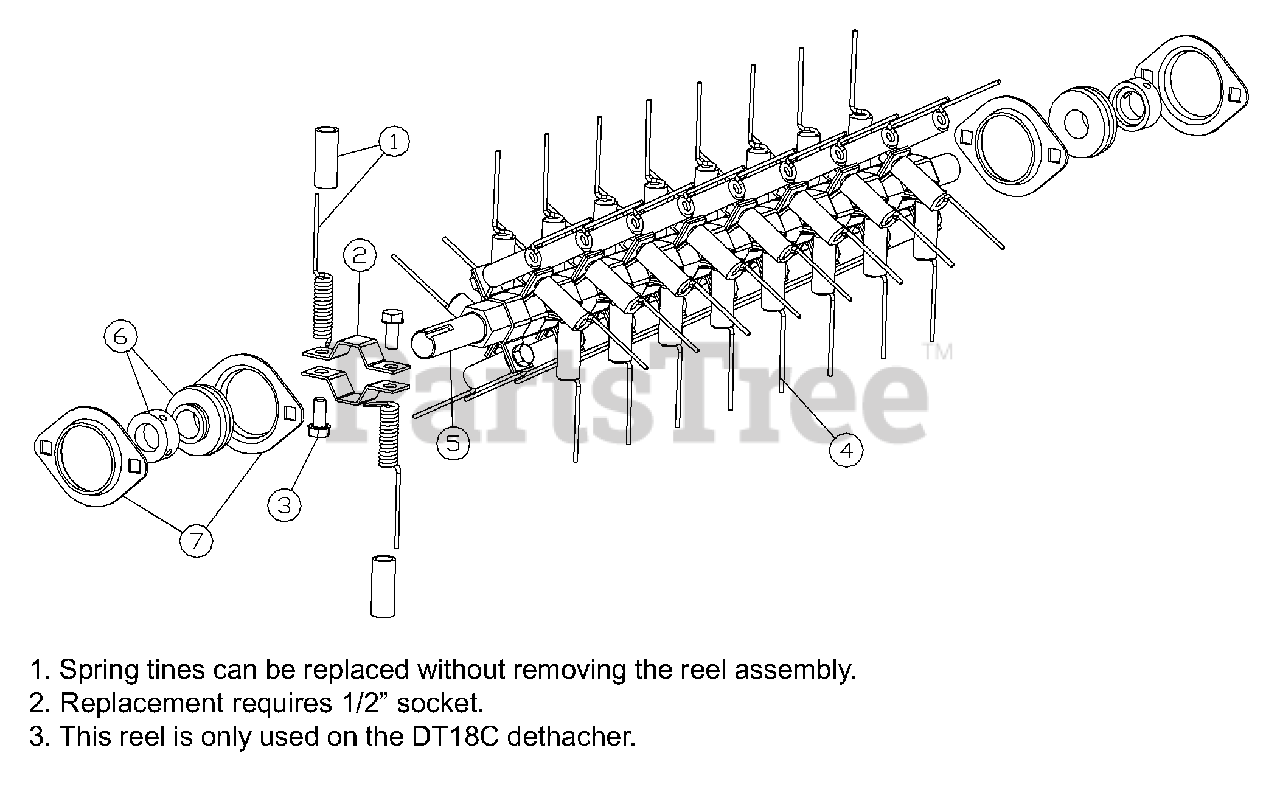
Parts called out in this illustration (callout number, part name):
1	Spring tine w/ sleeve
2	Clamp, tine
3	Screw for tine
4	Reel tine assembly
5	Shaft, tine reel
6	Bearing, 3/4 with locking collar
7	Stamping kit
